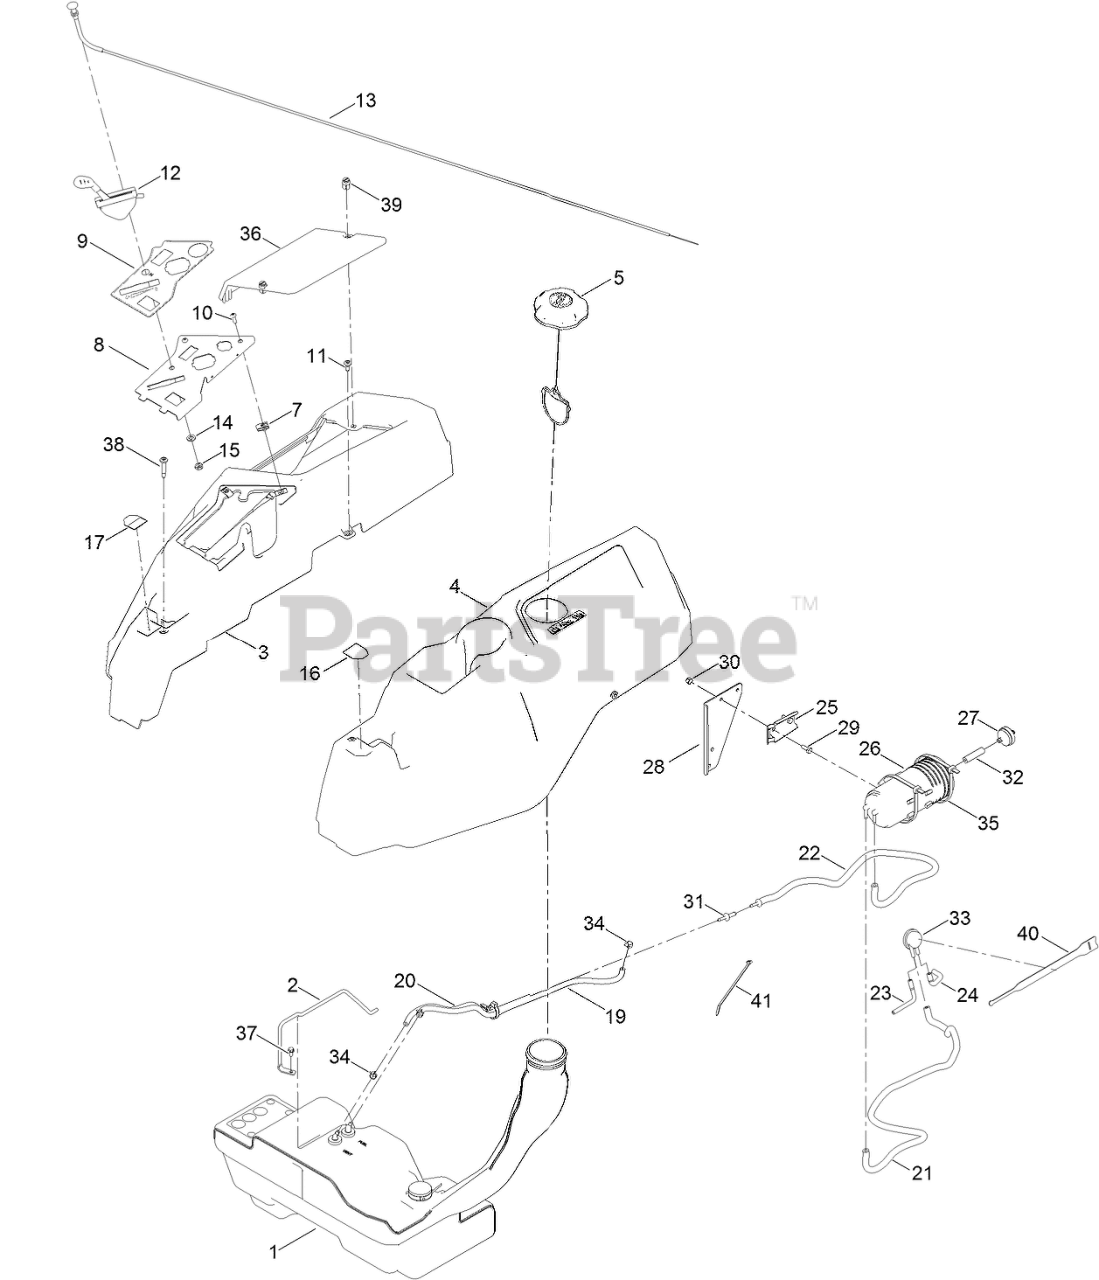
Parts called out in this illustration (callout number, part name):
1	FUEL TANK ASM
2	ROD-HOLD DOWN
3	POD-RH
4	POD-LH
5	CAP-FUEL, RATCHETING
8	PANEL-CONTROL
9	DECAL-CONTROL W/CHOKE
10	SCREW-PRH
11	SCREW-SHOULDER
12	CABLE-THROTTLE
13	CABLE-CHOKE
14	WASHER-LOCK
15	NUT-HJ
16	DECAL-LEVER, CONTROL (LH)
17	DECAL-LEVER, CONTROL (RH)
19	HOSE-FUEL
20	HOSE-FUEL
21	HOSE-FUEL
22	HOSE, FUEL
23	HOSE-VENT, FORMED
24	HOSE-VENT, FORMED
25	BRACKET-CANISTER, CARBON
26	CANISTER-CARBON, 800CC
27	FILTER-FUEL, INLINE
28	CARB CANISTER BRACKET
29	SCREW-HH
30	NUT-LOCK, NI
31	ADAPTOR-ORIFICE
32	HOSE-FUEL
33	VALVE-CONTROL, VACUUM
34	CLAMP-HOSE
35	TIE-CABLE
36	COVER-BATTERY
37	SCREW-HWH
38	SCREW-SHOULDER
39	FASTENER
40	STRAP-VELCRO, CABLE TIE
41	TIE-CABLE
